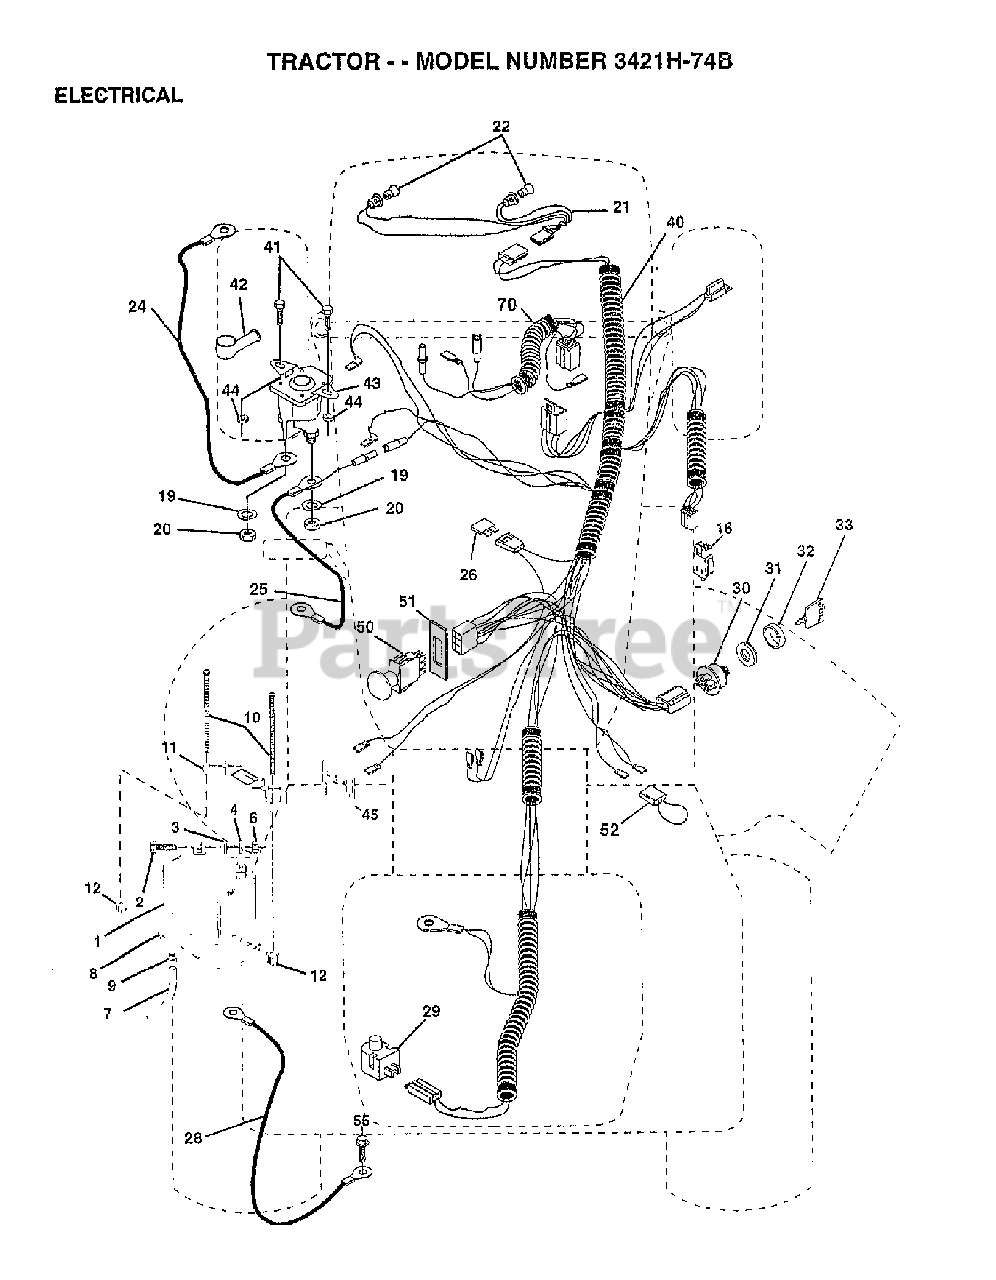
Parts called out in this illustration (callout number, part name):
2	BOLT.HEX.1/4.X.3/4.DICHROMATE
3	WASHER
4	LOCKWASHER
6	NUT
7	BATT DRAIN TUBE T
8	TRAY.BATTERY
9	HOSE CLAMP T
10	BOLT 1/4-20 X 7.5
11	BATTERY HOLDDOWN
20	NUT
22	LIGHTBULB
24	CABLE BATTERY 6 GA 22" W/16W
25	BATTERY CABLE
26	FUSE *
28	CABLE GROUND 6 GA 21" 90T BLK
29	SWITCH SEAT
30	SWITCH.IGNITION.4.POSITION
31	NUT
32	COVER KEY IGNITIO
33	KEY.MOLDED.GENERIC
41	BOLT
42	TERMINAL COVER
43	Solenoid Kit, .95
44	NUT.HEX.KEPS.1/4-20
51	RETAINING RING
52	WIRE PROTECTION LOOP
55	SCREW LT
